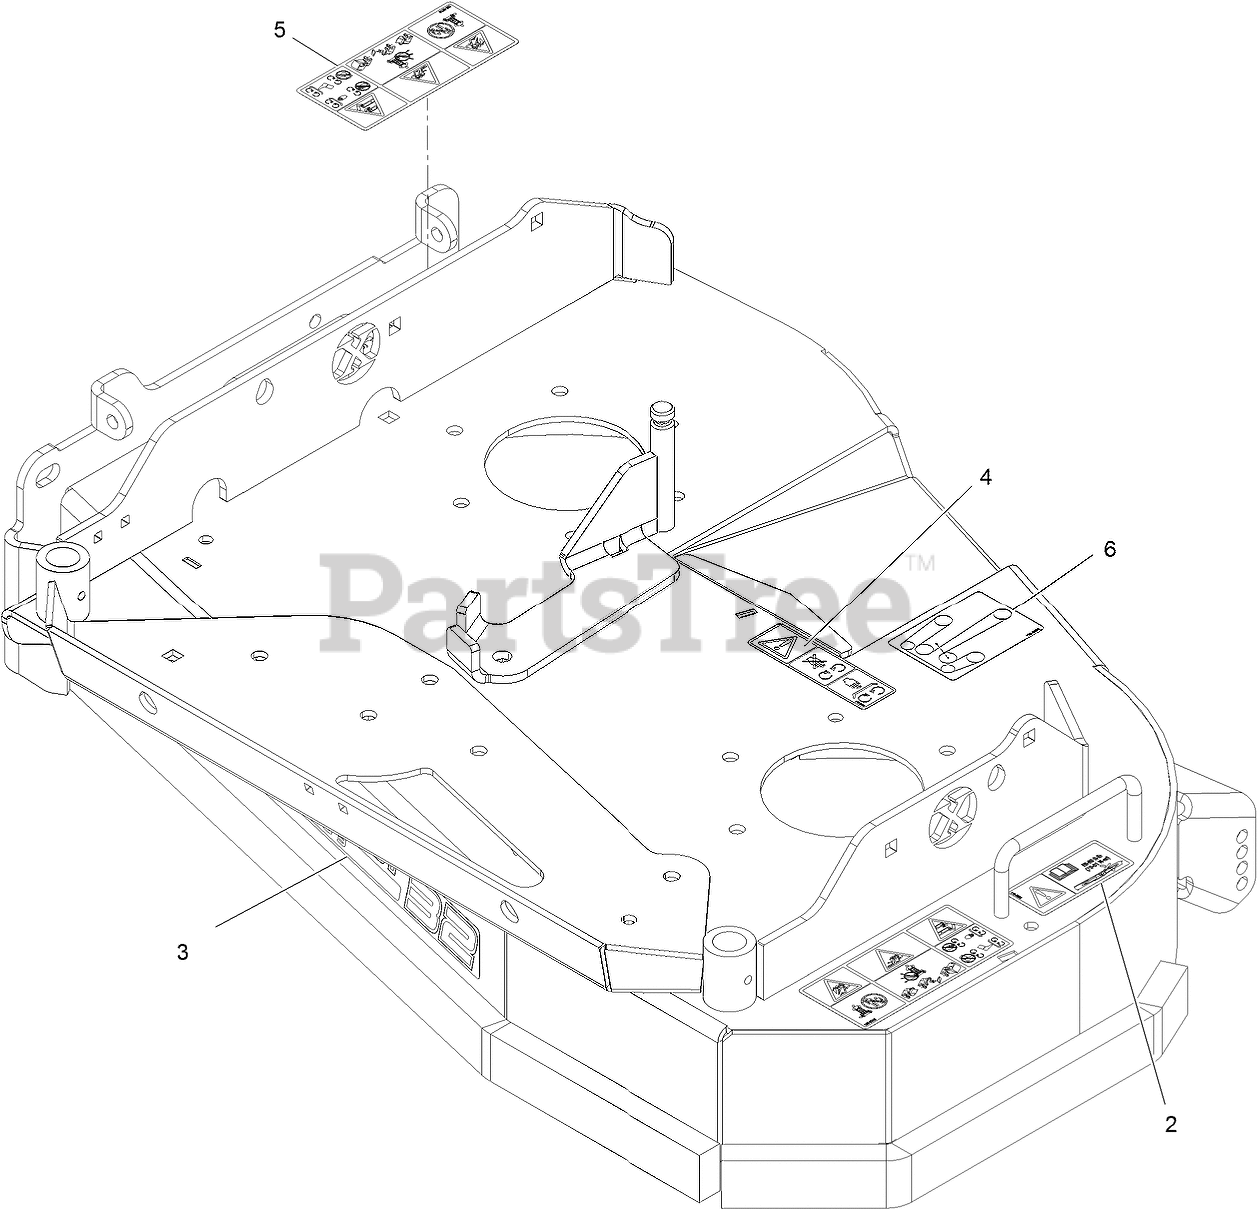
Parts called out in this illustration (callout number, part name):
2	DECAL-BOLT TORQUE
3	Decal-Ultracut 32-Series 3
4	DECAL-COVER, MISSING
5	DECAL-WARNING THROWN OBJ
6	Decal-Belt Routing
